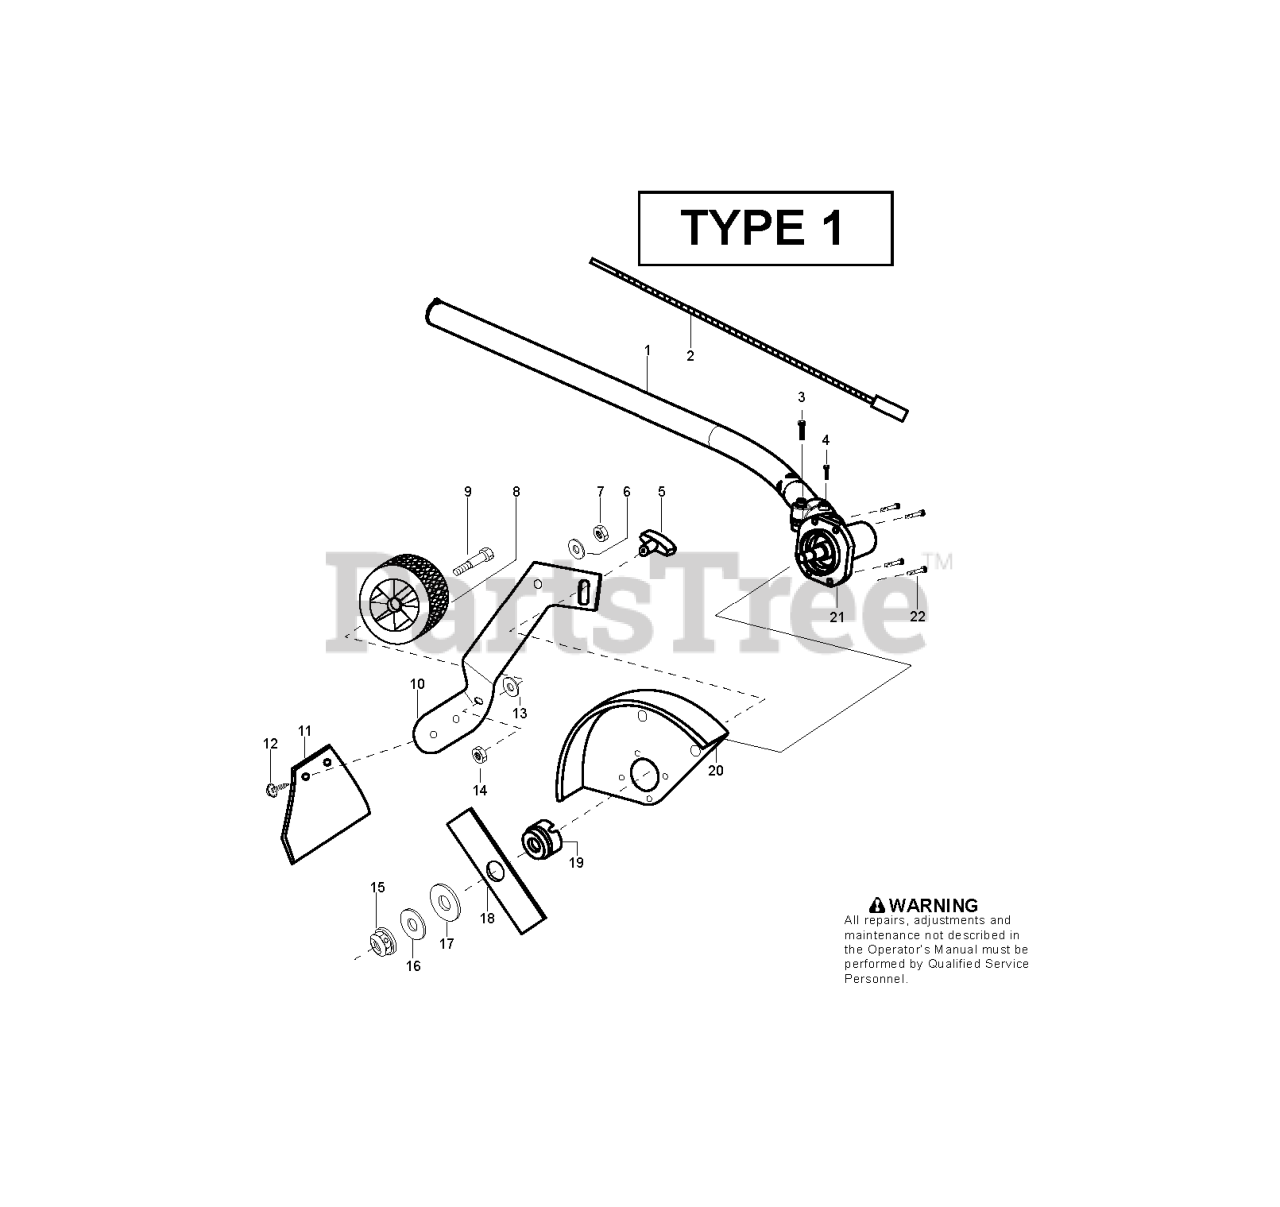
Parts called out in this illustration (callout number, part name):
1	DRIVE SHAFT
2	FLEX SHAFT (SPINED)
3	SCREW - CARB. ADAPTOR
4	SCREW 8-16 X 9/16 (PLAS
8	WHEEL-4"(FRONT)(RUBBER)
9	BOLT-SHOULDER AXLE
10	WHEEL BRKT ADJ
11	KIT MUD FLAP
12	FASTENER MUD FLAP
15	NUT-FLANGE (LH)
16	WASHER BELLVILLE
17	WASHER-FLAT.
20	SERVICE KIT FOR EDGER GUARD
22	SCR 10-24 MS LDK PAN PH
